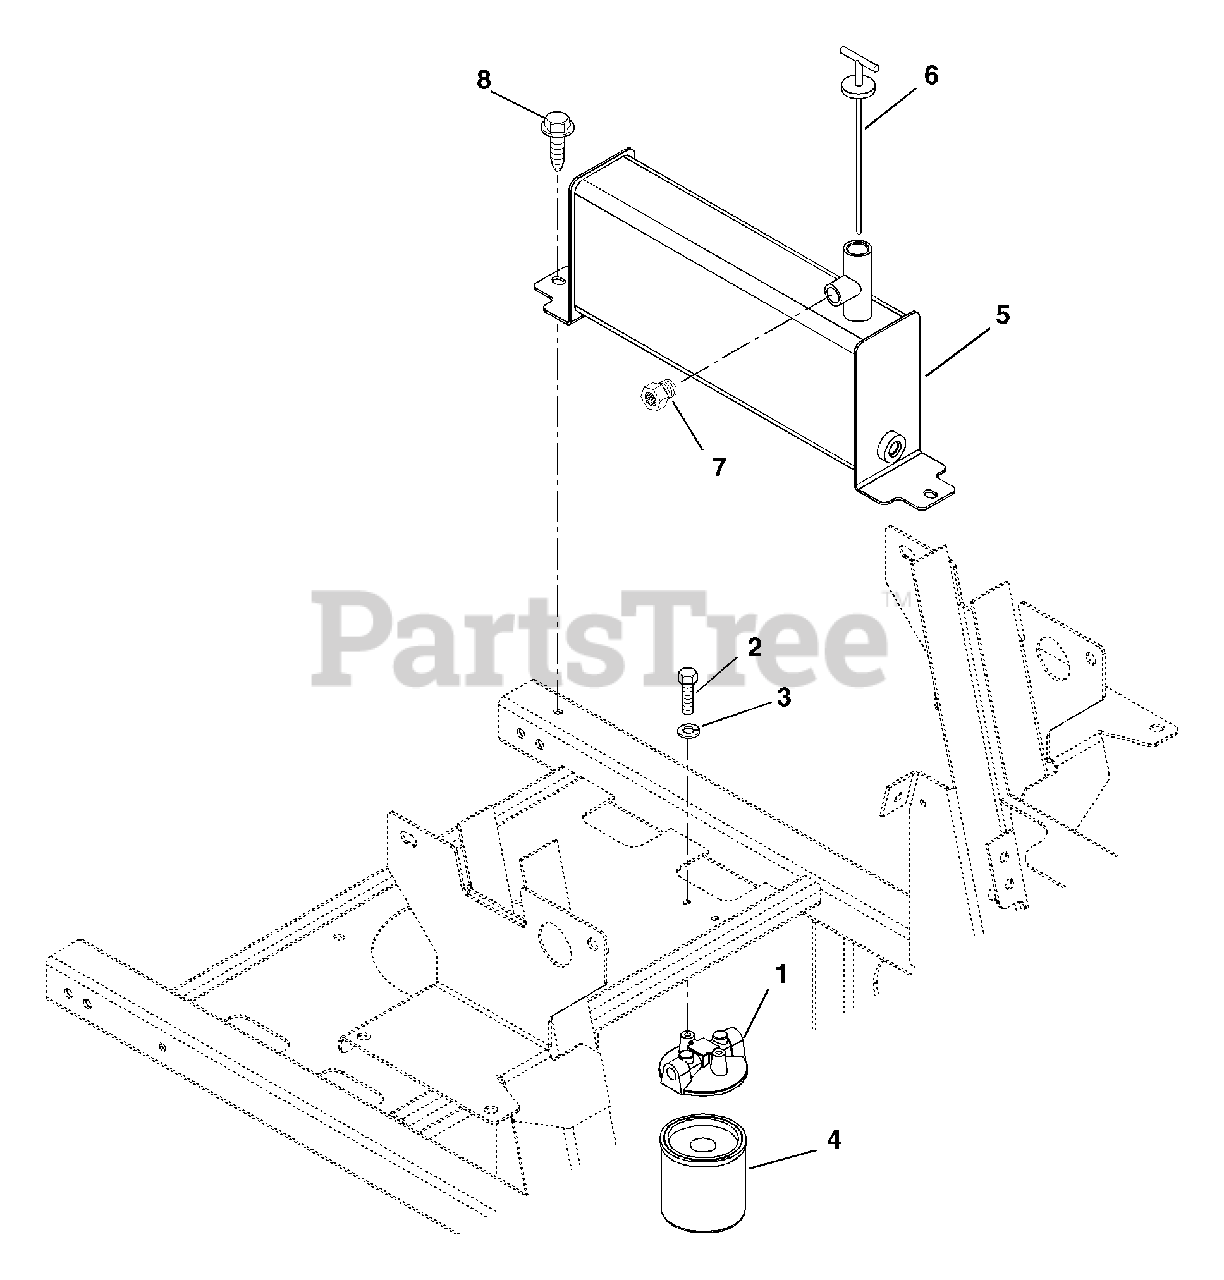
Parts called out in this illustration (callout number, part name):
1	Head-Filter
2	Bolt-Hex .25-20 x .50 Grade 5
3	Washer-Locking .25 x .062
4	Oil Filter
5	Tank-Hydraulic Weldment
6	Hydraulic Tank Dipstick
7	Plug-Breather .38
8	Screw-Tapping .38-16 x .75 Hex Washer Head
